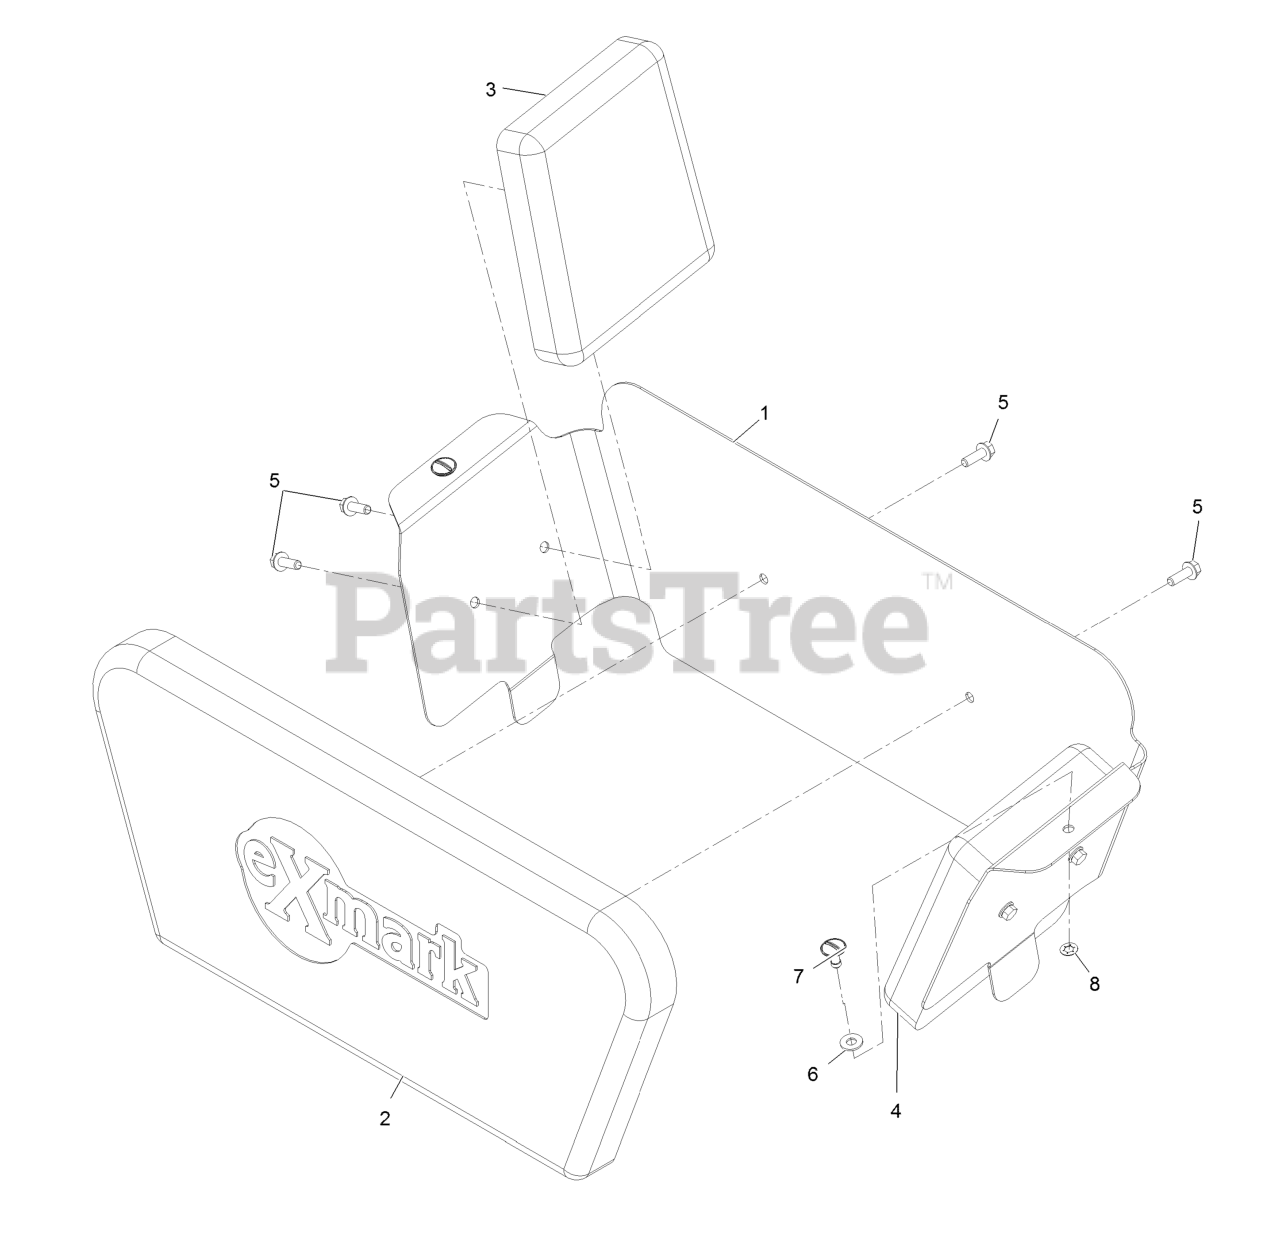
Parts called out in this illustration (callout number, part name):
1	Bracket-Pad, Knee
2	Pad-Knee, Center
3	Pad-Knee, LH Side
4	Pad-Knee, RH Side
5	Screw-Hex Flange 1/4-20 X 3/4
6	Washer-Flat
7	Stud-1/4 Turn
8	Retainer-Stud
